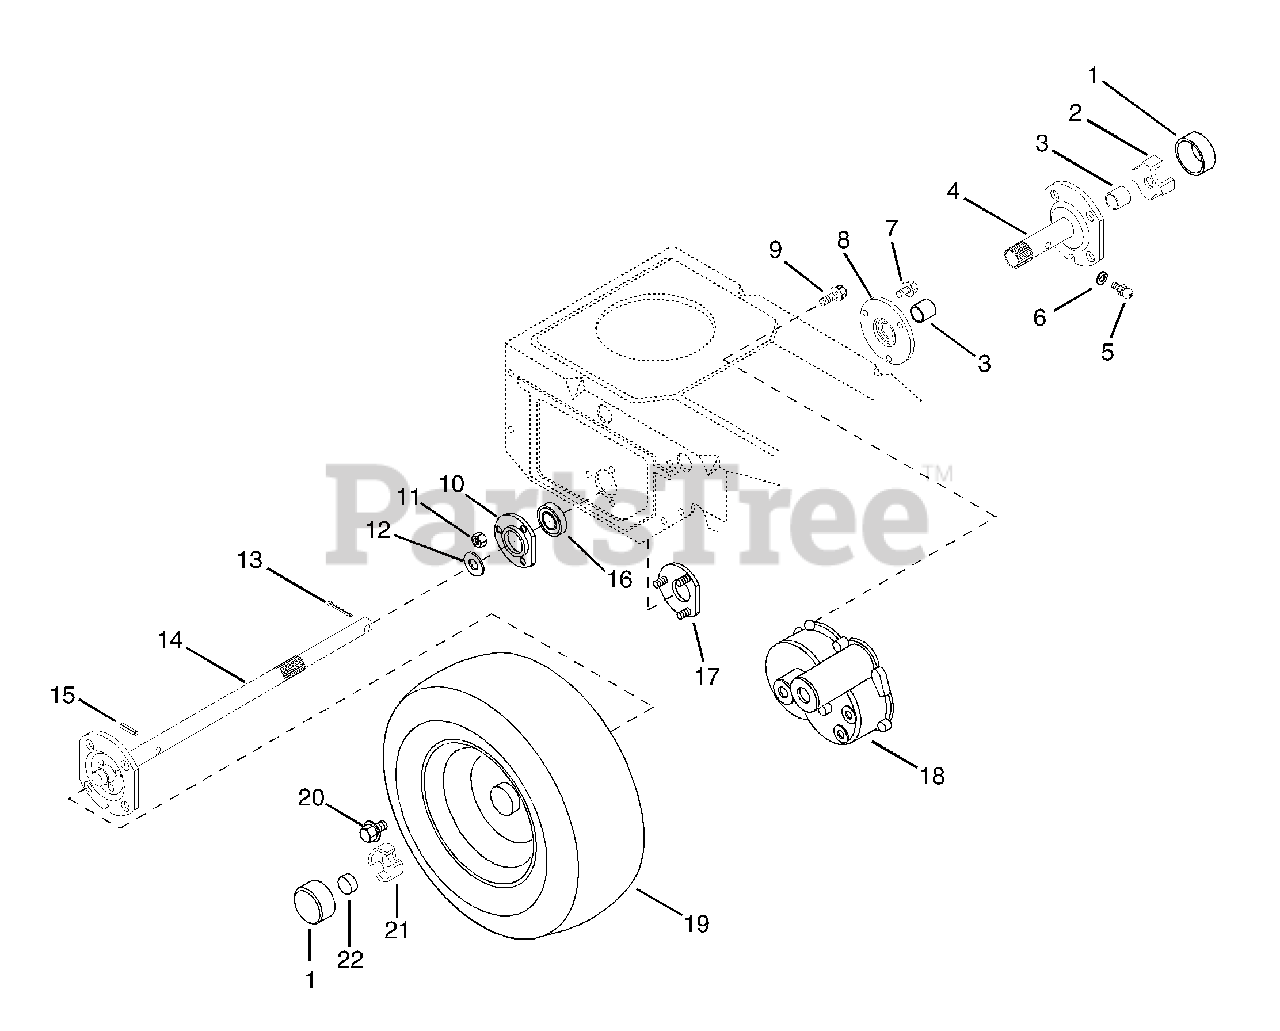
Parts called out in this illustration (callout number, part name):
1	HUB CAP
2	SPINDLE CUP
3	BSHG-SLV .690X.814X1.000 BR
4	L.H. AXLE ASSEMBLY
5	FTG-LUBE .25-28X.256 YWZC
6	WSHR-LK .250X.047 LT YWZC
7	@SCR-TAP .25-20X.50 HWH TR YWZ
8	SEAL 1.125X2.496X.380
9	@SCR-TAP .31-18X1.50 HWH TR YZ
10	BEARING FLANGE
11	@NUT-SPNLK-FLG .25-20 YWZC
12	WSHR-FL-STL .880X1.380X.062
13	@PIN-CTR .12X1.00 EXTPRSQCT YZ
14	RH AXLE
15	PIN-ROLL .188X1.25
16	BRG-BALL .876 X 1.750 X .50
17	BEARING FLANGE
18	GEAR CASE ASSEMBLY
19	T/WHL ASSY 6.50-8 X 16
20	SCR-TAP .500-20X.62 HH YWZC
21	SPINDLE CUP
22	PUSHNUT
